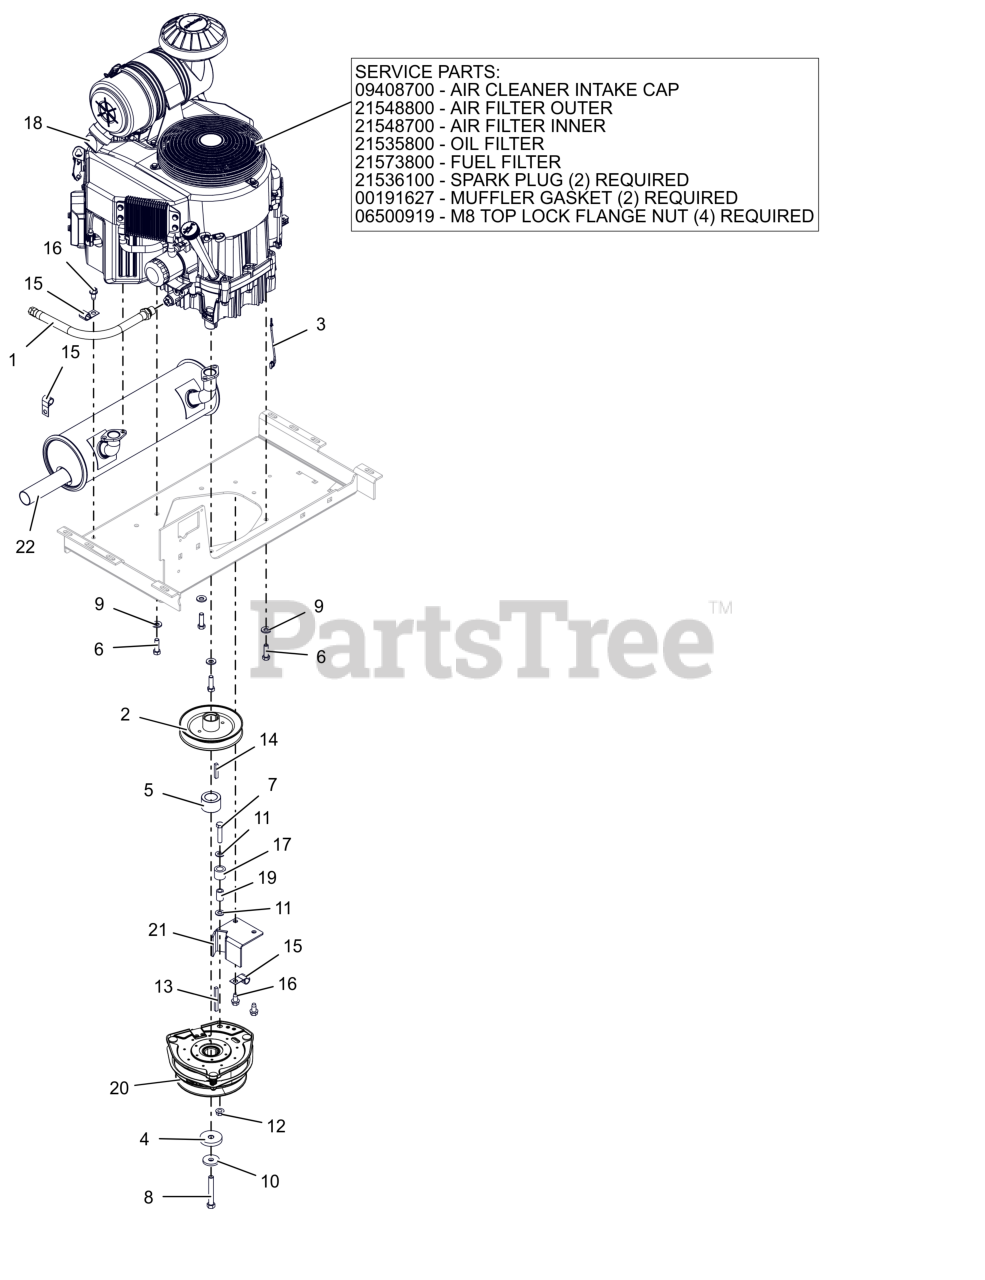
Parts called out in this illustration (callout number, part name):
1	HOSE, OIL DRAIN
2	WLDMT, TRANSAXLE DRIVE PULLEY
3	LEAD - STARTER SOLENOID
4	SPACER, .474/.459X2.00X.350
5	SPCR, 1.125 x 1.750 x 1.147
6	BLT, HEX .38-16X1.25 G5 ZCC NT
7	BLT, HEX .38-16X1.75 G5 ZCC
8	BLT, HEX 0.4375-20X3 G8 ZCC NT
9	WASHER, 3/8" SPRING DISC
10	WASHER, 7/16" SPRING DISK
11	WSHR,FLT .406X.812X.065 ZCC
12	NUT-LK-CTR-FLG .375-16 GF ZCC
13	KEY-SQ .25 X 2.50 X .25 SAE
14	KEY-SQ .25 X 1.50 X .25 SAE
16	SCR,TAP .375-16X.75 HWH TR ZCC
17	BUMPER,RUBBER .62X1.0X.88 LG
18	ENGINE, KAWASAKI FX850
18	CAP, AIR CLEANER INTAKE (2")
18	FILTER, OUTER
18	FILTER, INNER - KAW
18	FILTER,OIL - KAW
18	FUEL FILTER
18	PLUG, SPARK
18	GASKET, MUFFLER S/O
18	NUT-LK-TOP-FLG M8 ZCC
19	BUSH.,S.391X.622X.950 ST
20	CLUTCH, OGURA GT3.5-AR04
21	WLDMT, CLUTCH STOP (BLACK)
22	MUFFLER, KAWASAKI FX850
